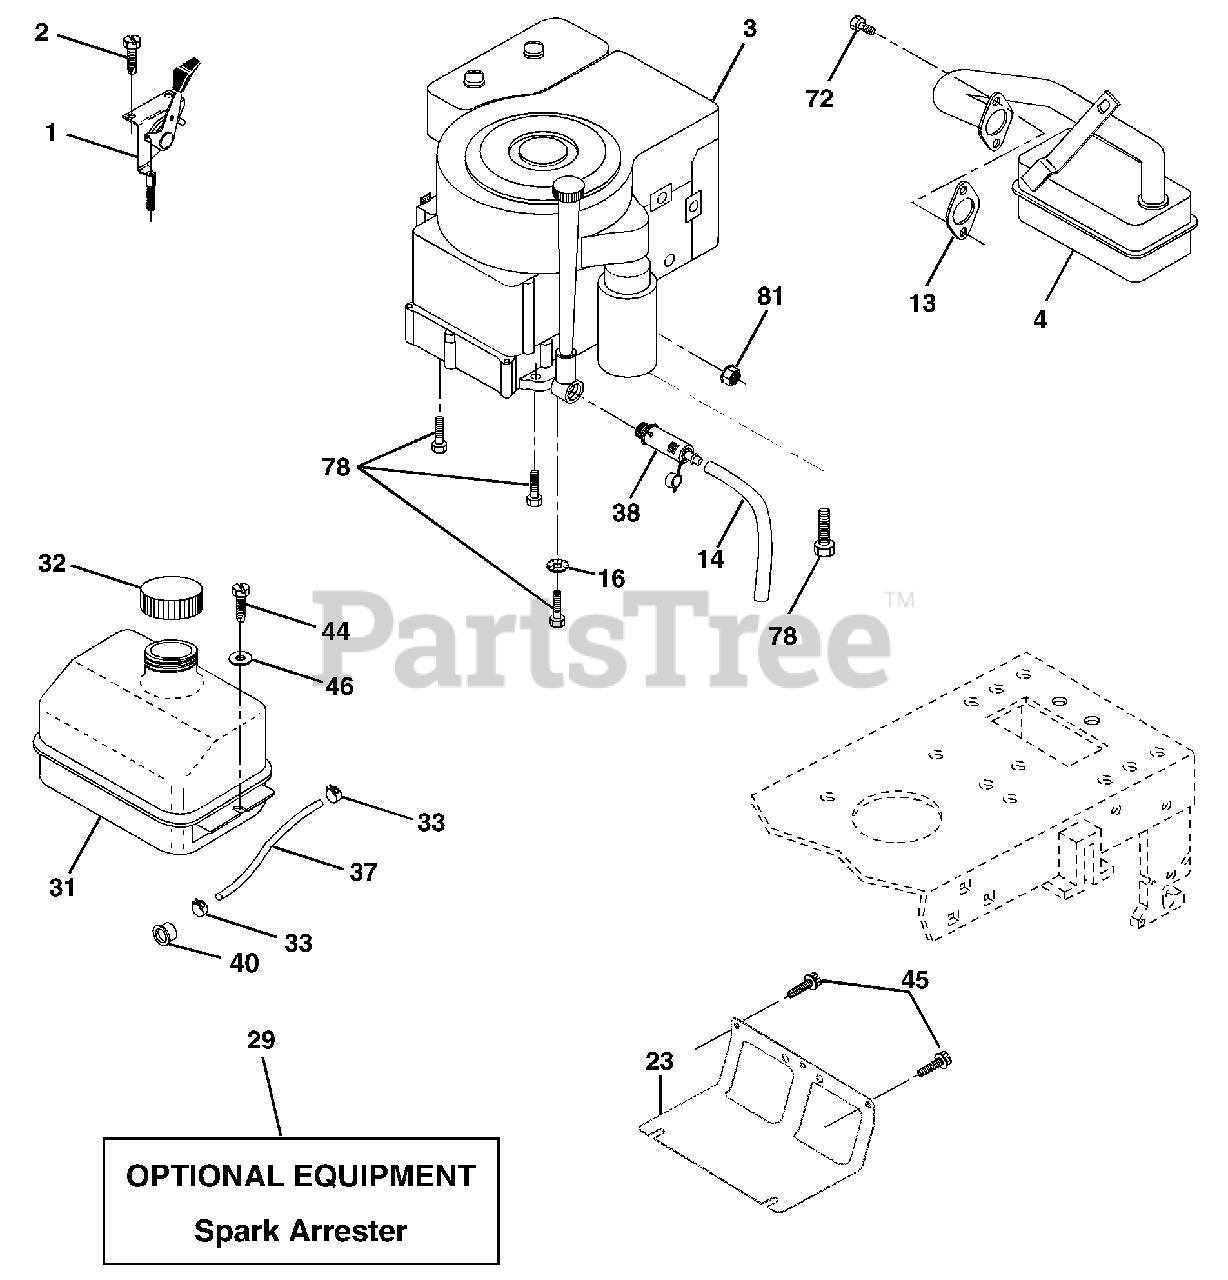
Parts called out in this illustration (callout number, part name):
1	Control Th/ch Flag
2	Screw Hex Thd Cut 1/4-20 x 1/2
4	Muffler Exhaust B&S
13	Gasket Eng 1 313 Id Tin Plated
14	Tube Drain Oil Easy
16	Washer Lock Ext Tooth 3/8
23	Shield BRN/DBR Guard
29	Kit Spark Arrestor (Flat Scrn)
31	Tank Fuel Front
32	Cap Asm Fuel
33	Clamp Hose
37	Line Fuel 20"
38	Plug Drain Oil
40	Bushing Snap Nyl Blk Fuel Line
44	Screw Thdrol 1/4-20 x 3/4
45	Screw Hex Wsh Thdrol 3/8-16
46	Washer 9/32 X 7/8 X 16 Ga
72	Screw Socket Head 5/16-18 x 1
78	Screw 3/8-16 x 1-1/4
81	Nut Keps Hex 1/4-20 Unc
